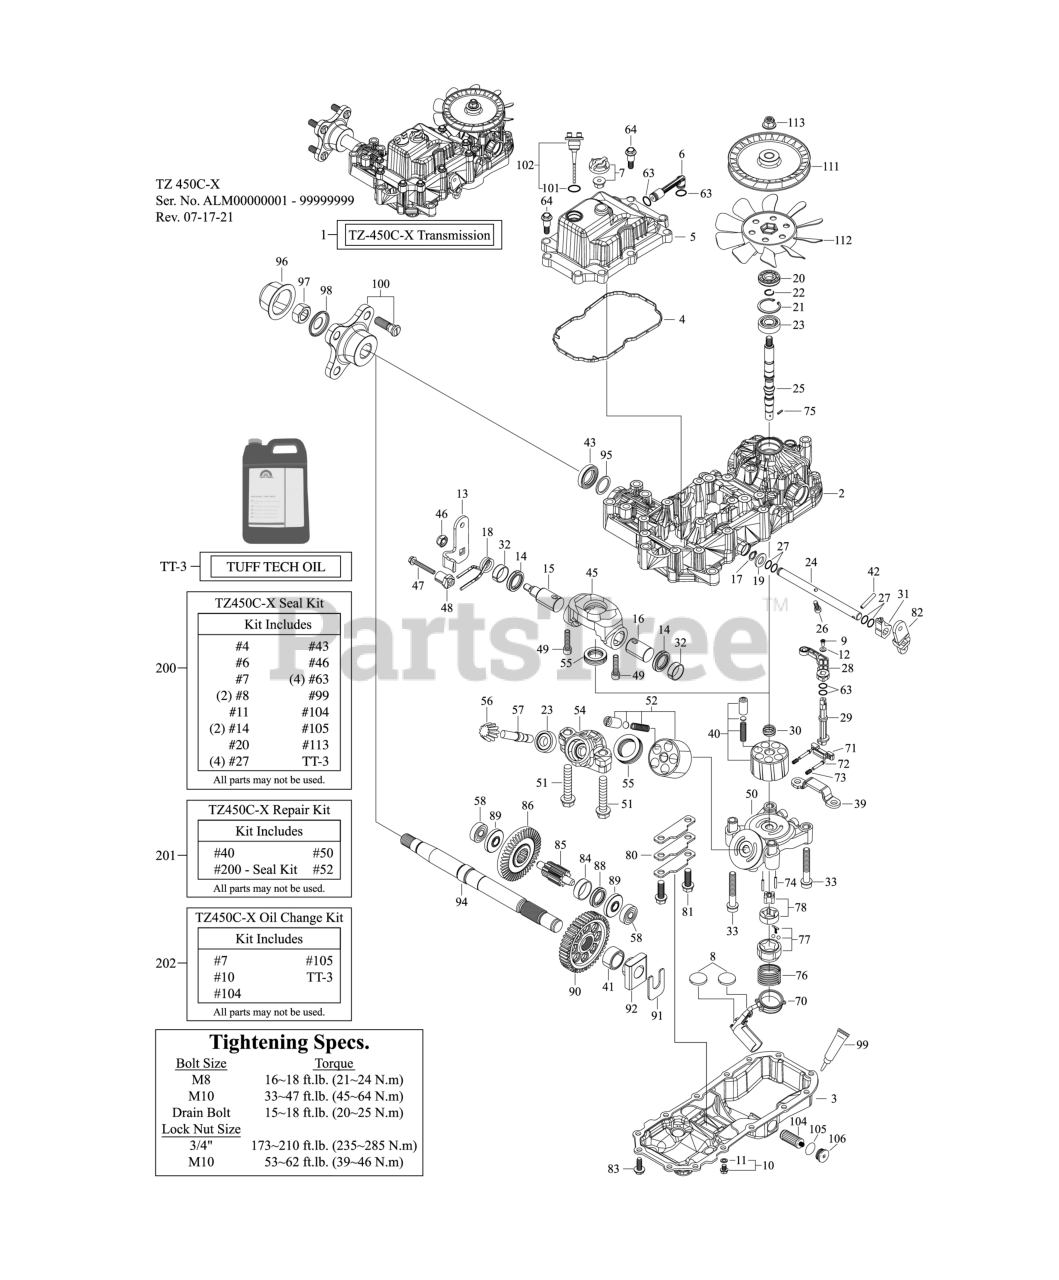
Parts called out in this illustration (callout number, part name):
1	Transaxle - Tuff Torq, LH - SZL
2	Upper Housing X
3	Lower Housing Fy
4	Square Seal
5	Top Cover A
6	Bypass Piping
7	Vent Valve
8	Magnet 28 * 3.5
9	Screw 4.0*8
10	Drain Bolt Kit
11	Washer Seal 10
12	Washer 4.5*10*1
13	Control Lever L
14	Seal, Tc253506
15	Control Shaft
16	Control Shaft Short
17	Snap Ring
18	Torsion Spring
19	Washer 12
20	Oil Seal 15*35*07
21	Snap Ring C 35
24	Brake Shaft
25	Pump Shaft C
26	Socket Bolt 6*16
27	O-Ring 1a P12
28	Bypass Lever
29	Bypass Shaft
30	Pump Spring
31	Brake Fork 20 Cr
32	Control Bush Lfb2510
33	M10 * 65 Bolt
39	Check Stopper Pfg
40	Cylinder Block Kit / Order Repair Kit
41	Bushing 25.4
42	Spring Pin 5 * 32
43	Seal Tc284008
45	Swashplate
46	Lock Nut 10
47	Bolt 6*45
49	Bolt 8 * 35
50	Centercase Cp / Order Repair Kit
51	Bolt 12*65
52	Cylinder Block Kit(Motor / Order Repair Kit
54	Motor Housing
55	Thrust Bearing
56	Motor Gear S
57	Motor Shaft
58	Bearing 6201 Cn
63	0-Ring 1a P10a
64	Tapping Bolt 8*30
70	Bracket Assy Fts
71	Bypass Guide
72	Bypass Pin
73	Bypass Spring
74	Pin 3.0 * 18
75	Pin 2.5* 9.8
76	Charge Spring
77	Pump Case
78	Rotor Set
80	Final Plate
81	Bolt 10 * 30
82	Brake Arm
83	Tapping Screw 8 * 20
84	Final Pinion Collar
85	Final Pinion Shaft
86	Reduction Gear S
88	Reduction Collar
89	Reduction Collar
90	Final Gear Sv
92	Bushing 25.4
94	Axle Shaft T
96	Nut Cap
97	Lock Nut 3/4-16
98	Flange Spacer
100	Flange Assy.
101	O-Ring 1a P16
102	Dipstick Assy.
104	Filter
105	O-Ring 1a 24040
106	Cap 40
111	Pulley,5.5
112	Fan
113	Lock Nut 10
200	Seal Kit Tz-450
201	Repair Kit Tz-450 C
202	Tz 450 Oil Change Kit
TT-3	Tuff Tech Oil (3 Liter Bottle)
